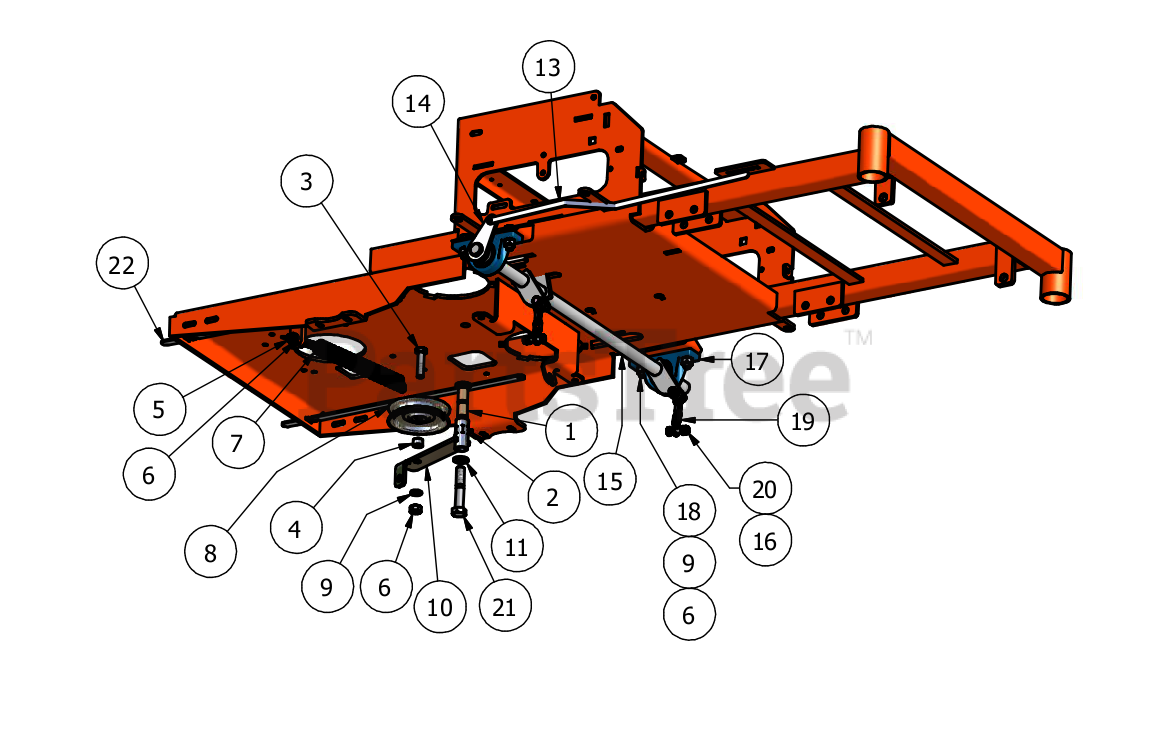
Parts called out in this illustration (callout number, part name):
1	Bronze Bushing
2	Grease Fitting
3	1/2" x 2" Bolt
4	1/2" Spacer
5	Spring Tensioner
6	1/2" Hex Nut
7	Pump Idler Spring
8	4 3/4" Idler Pulley
9	1/2" Lock Washer
10	Pump Idler Bracket
11	5/8" Nylon Washer
12	5/8" Nylock Nut
13	Height Indicator Bar
14	Height Indicator Lever
15	Actuator Bar - Transaxle
16	3/8" Nylock Nut
17	Pillow Block Bearing
18	1/2" x 1 1/2" Hex Bolt
19	Deck Chain
20	3/8" x 1 1/2" Bolt
21	5/8" x 4" Hex Bolt
22	Transaxle Neutral Lever
